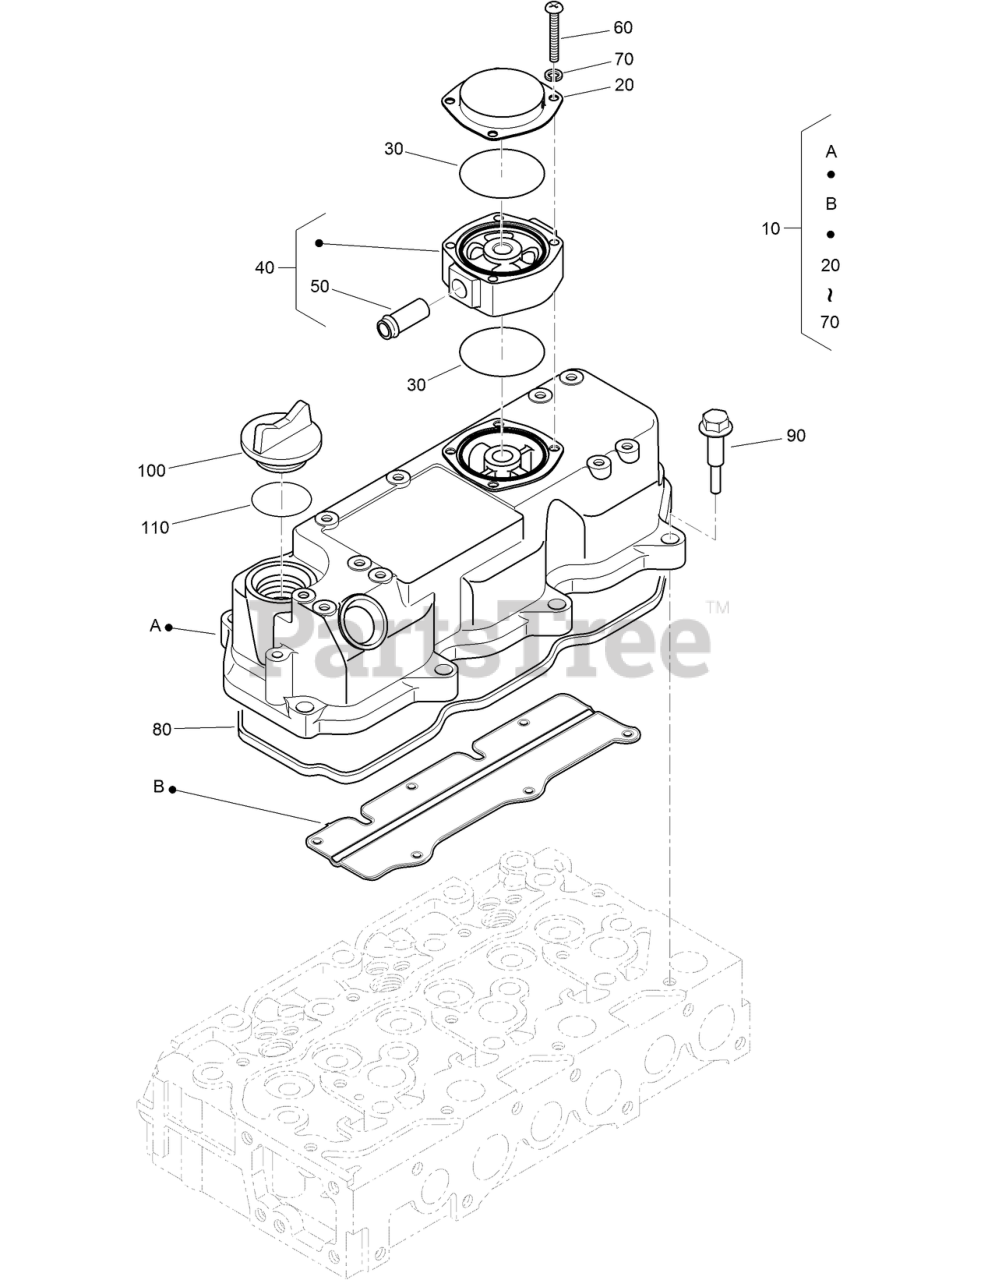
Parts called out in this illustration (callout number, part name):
10	HEAD COVER ASM
20	COVER-BREATHER
30	O RING-BREATHER
40	SPACER-BREATHER
50	PIPE-RETURN, WATER
60	SCREW-PHILLIPS, PAN HEAD
70	WASHER-LOCK, SPRING
80	GASKET-COVER, HEAD
110	O-RING
